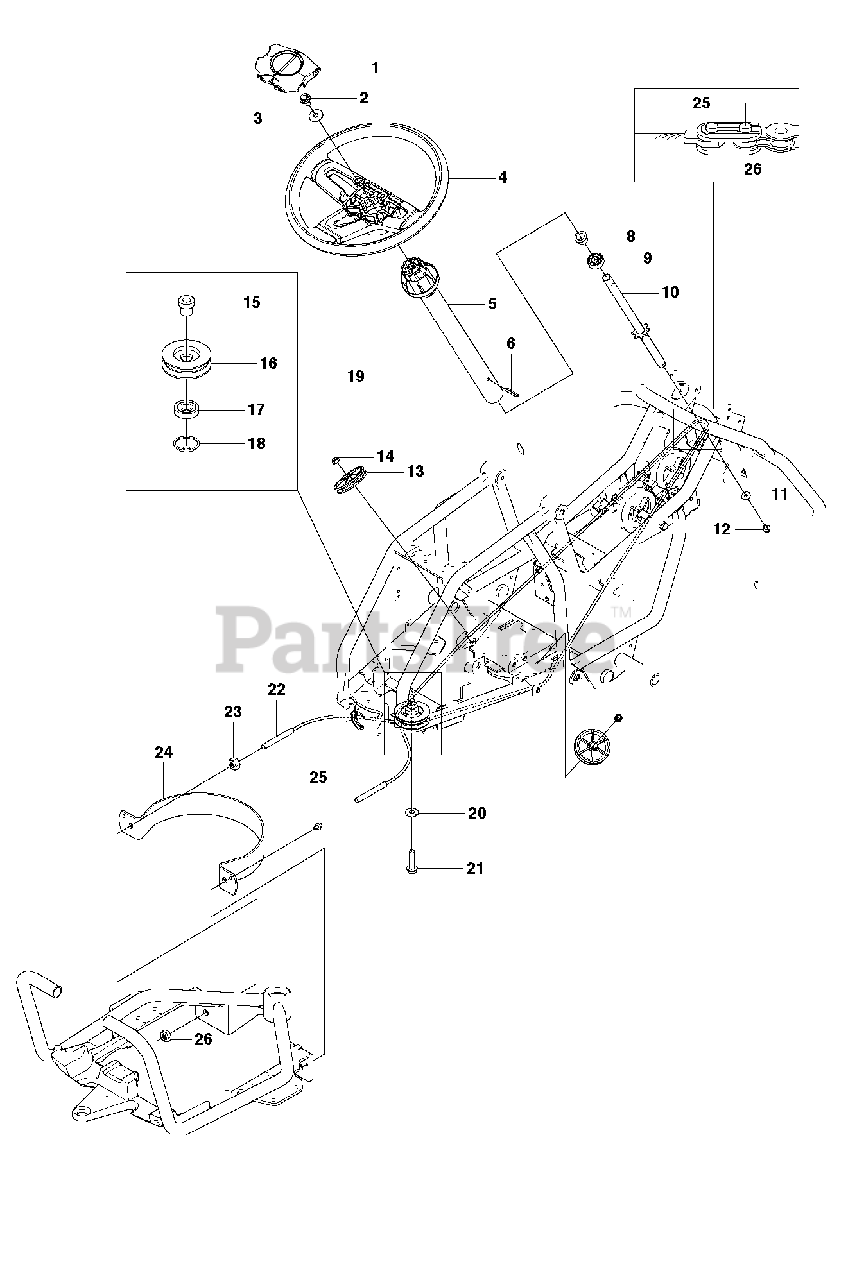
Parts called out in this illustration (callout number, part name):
9	BALL BEARING 6004-2RS1
11	WASHER - 26X6.5X1.6
12	SCREW EHHFM
14	LOCKNUT M6
17	BALL-BEARING 6204-2RS
18	CIRCLIP SGH 47
19	STEERING ASSY
22	WIRE ASSY
26	STEERING CHAIN
